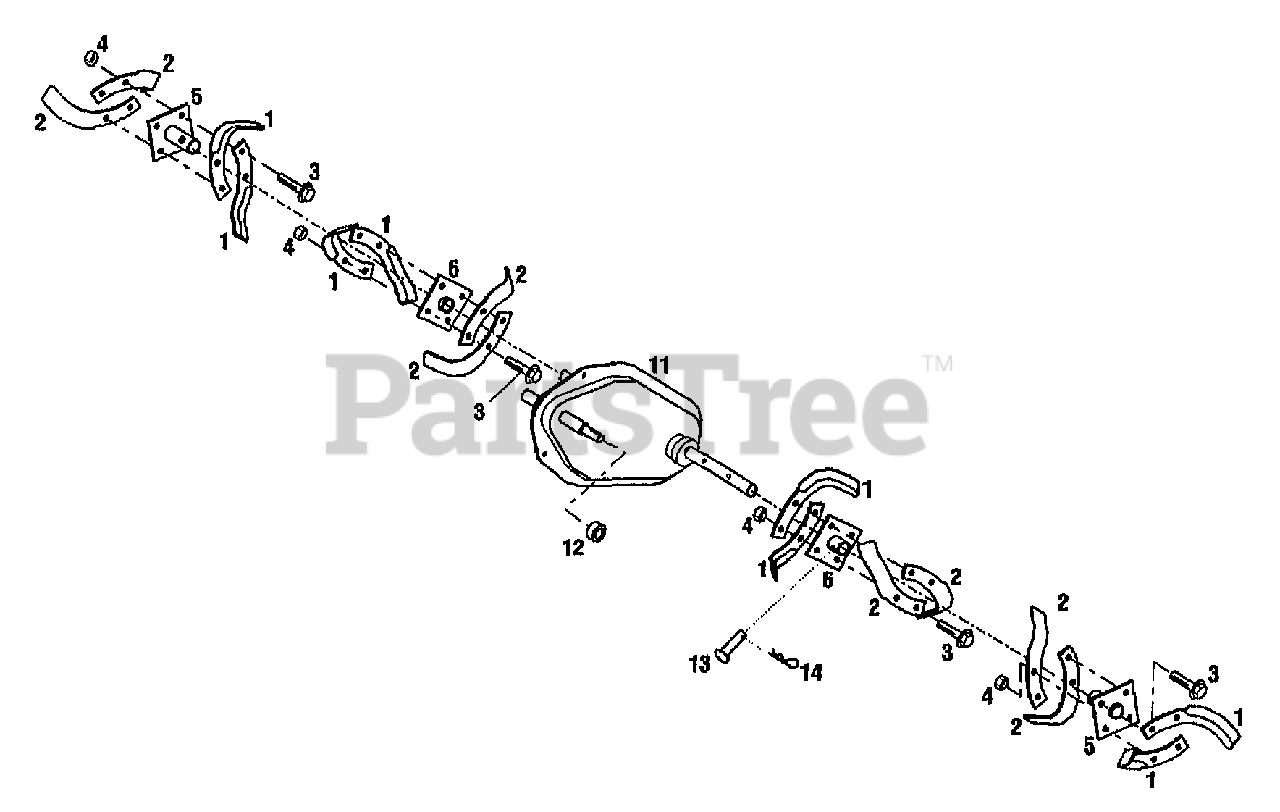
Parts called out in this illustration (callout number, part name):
1	TINE-BOLO LT W/HDW
2	TINE-BOLO RT W/HDW
3	SCR-HH 3/8-16X1.0 G5 ZP
4	NUT-H/LK 3/8-16
5	ASSM-OUTER HUB
6	ASSM-INNER HUB
11	ASSM-TRANSMISSION
12	BEARING-COLLAR
14	PIN-HITCH
15	TINES-BOLO HORSE/PONY/ECONO
